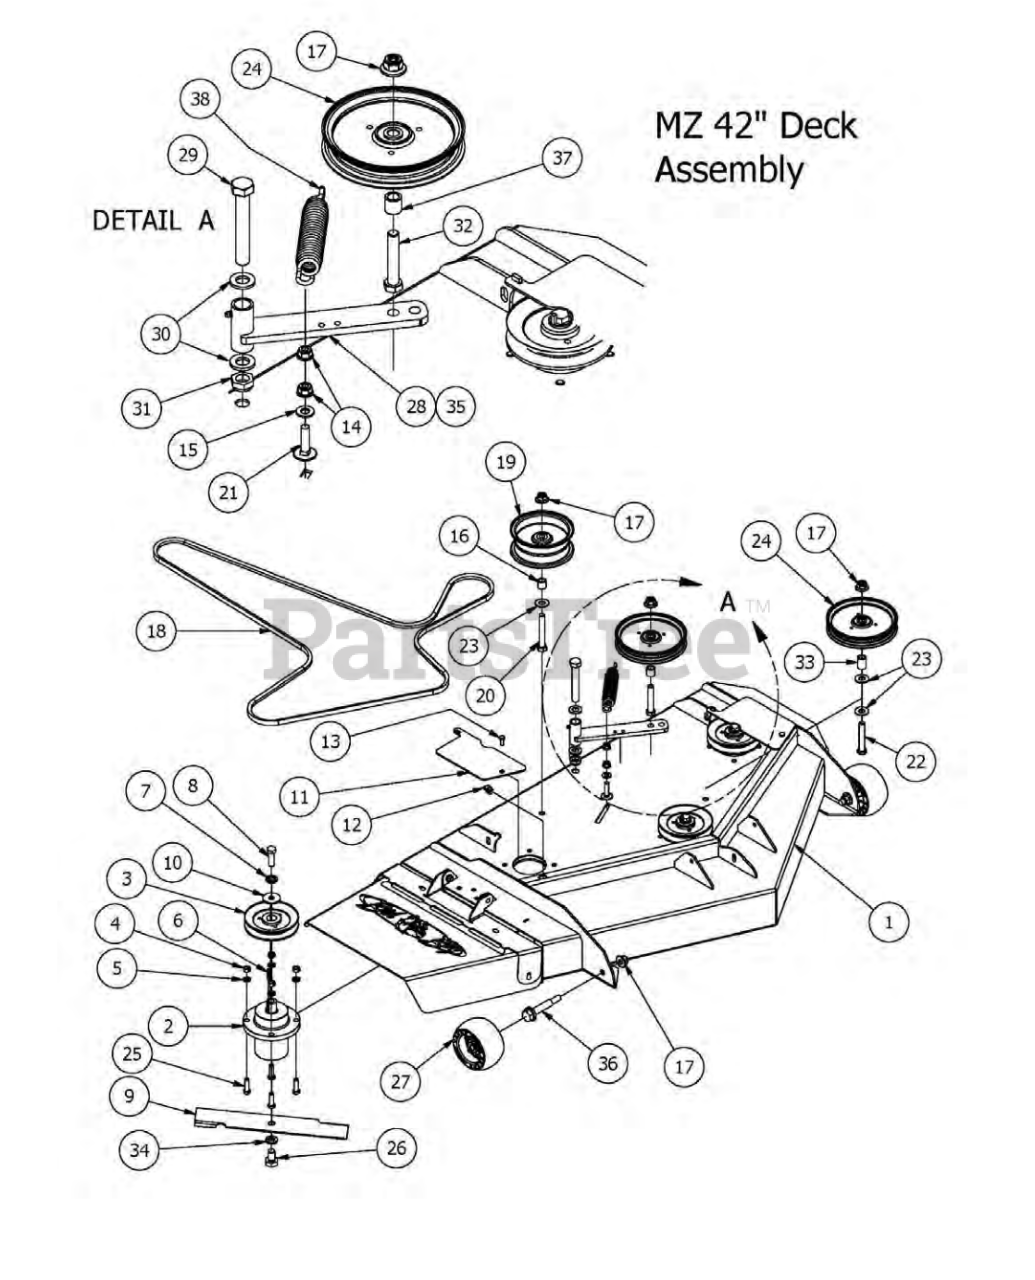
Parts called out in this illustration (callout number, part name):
1	Mz 42 Deck
2	Spindle Assembly
3	MZ Deck Pulley
4	3/8-16 Hex Nuts Zinc
5	3/8 Lockwasher Zinc
6	3/16 x 1 Square Key
7	1/2" Lock Washer
8	1/2-20 x 1-1/2 Grade 5 Hex Bolt Zinc
9	MZ 42 Blade
10	1/2 Belleville Washer
11	MZ42 Pulley Cover
12	1/4-20 Cage Nut
13	1/4" x 3/4" Hex Bolt
14	3/8" Nylock Flange Nut
15	3/8" Flat Washer
16	Spacer 3/4 OD x 1/2 ID x 314 Length
17	1/2-13 Nylon Flange Nut
18	42" Deck Belt-B120
19	5 3/4" Deck Idler Pulley
20	1/2-13 x 3 1/2 GR 5 Hex Bolt
21	3/8 x 1-1/2 Carriage Bolt
22	1/2-13 x GR 5 Hex Bolt Zinc
23	1/2" Washer (Grade 8)
24	5-3/4 Idler Pully
25	3/8" x 1 1/4" Hex Bolt
26	5/8" x 1 1/2" Grade 8 Hex Bolt (Fine)
27	Anti-Scalp Rollers
28	Deck Idler 2009 AOS
29	5/8" x 4" Hex Bolt
30	.635 ID Plastic Washer
31	5/8-11 Nylon Insert Jam Half Nut
32	1/2" x 2 3/4" Hex Bolt
33	.502 x .750 x 1.25 Length Spacer
34	5/8" Lock Washer
35	MZ Deck Idler Assembly (Parts 17,24,30,34,and 37)
36	Deck Wheel Bolt
37	42/48 MZ Idler Pully Spacer
38	Deck Idler Spring MZ
